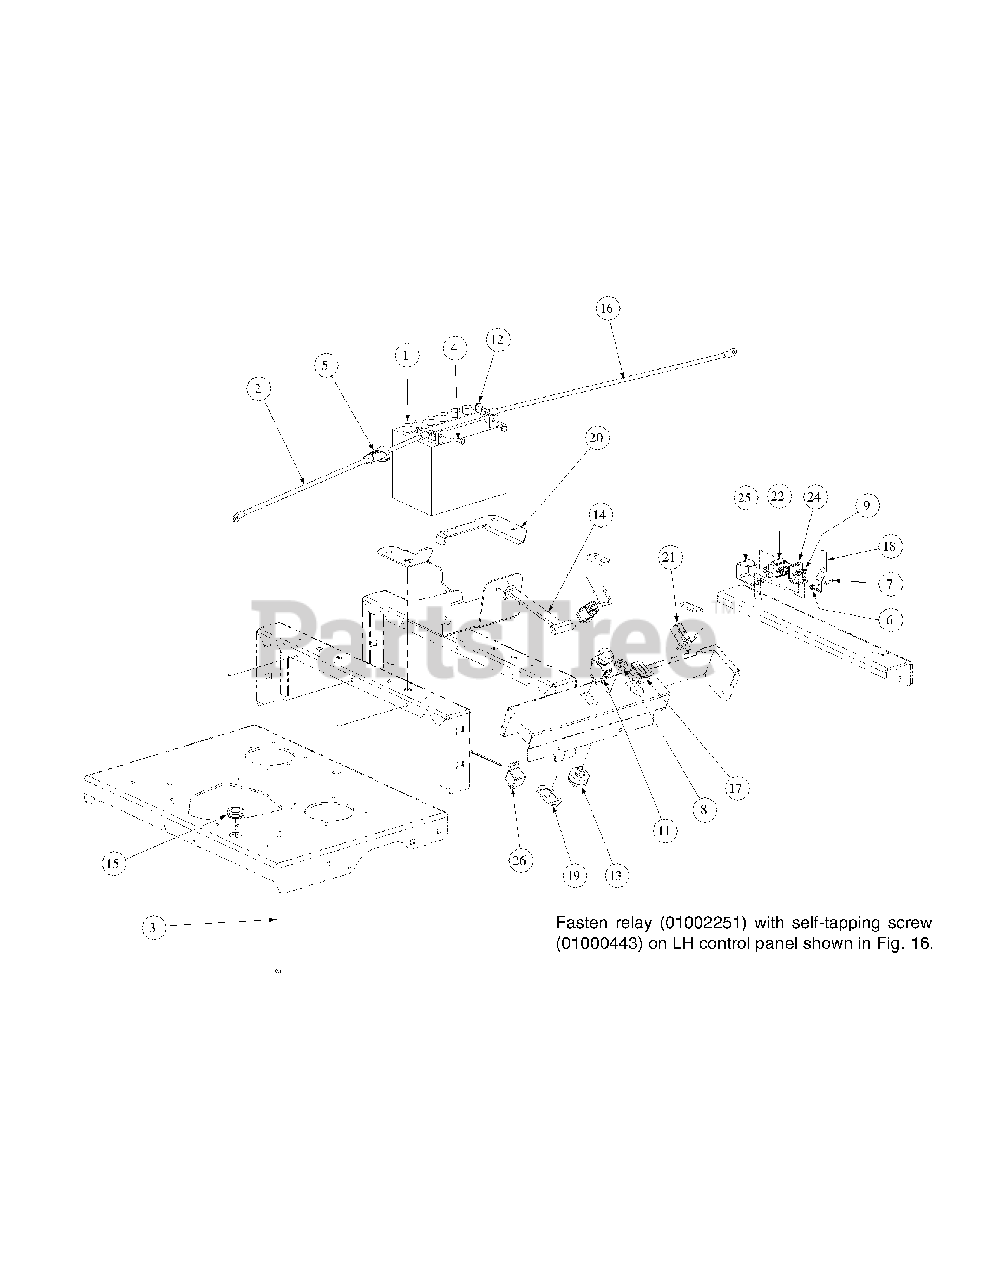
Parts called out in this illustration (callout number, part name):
1	Battery, 12V 225CCA 30 Min
2	Cable, Battery, Red, 36"
3	Tie, Cable, 3/16 x .05 x 7.4"
4	Screw, Hex, Cap, 1/4-20 x .75
5	Boot, 1" OD Rubber Battery-PST, Red
6	Lock Nut, Nylon Insert
7	Screw, Phillips Head, Machine, 10-32 x 5/8
8	Nut, W/Cap, 5/8-32 Ignition
9	Screw, TT, 1/4-20, 0.5, Hex Index Washer
10	Hourmeter, Harness
11	Switch, Electric, PTO
12	Lock Nut, 1/4-20
13	Switch, Ignition, 6 Pin
14	Strap, Battery
15	Grommet, .75 ID
16	Cable, Battery Red, 28"
17	Meter, Hour
18	Spring Retainer
19	Bracket, PTO Switch Retainer
20	Mount Bracket, Battery
21	Switch, Safety N.O./N.C.
22	Switch Plunger
23	Harness Assembly
24	Bracket, Plunger Switch
25	Clamp, Plunger Switch
26	Relay, 12V 40A
